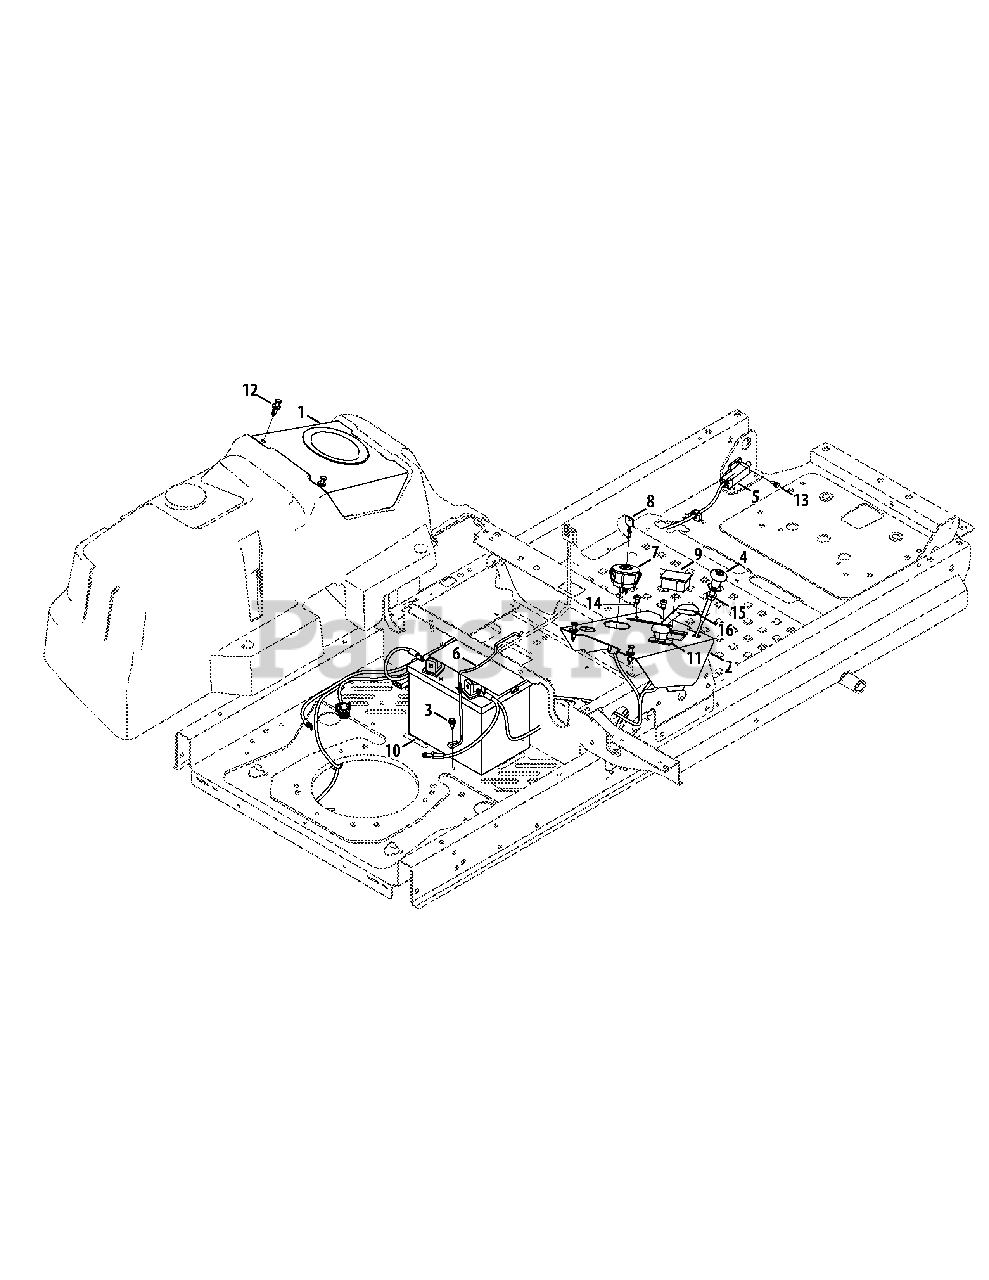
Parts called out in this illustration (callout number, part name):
1	Console Cover, LH
2	Console Cover, RH
3	Hex Washer Screw, 1/4-20 x .625
4	Choke Cable
5	Interlock Switch
7	Key Switch
8	Key, Assembly
9	Hour Meter/Service Minder
11	Electric PTO Switch
12	Plastic Rivet
13	Shoulder Screw, #10-32 x .500
14	Screw, 1/4-20 x .50
15	Flange Lock Nut, 3/8-16
16	Throttle Cable, Command
